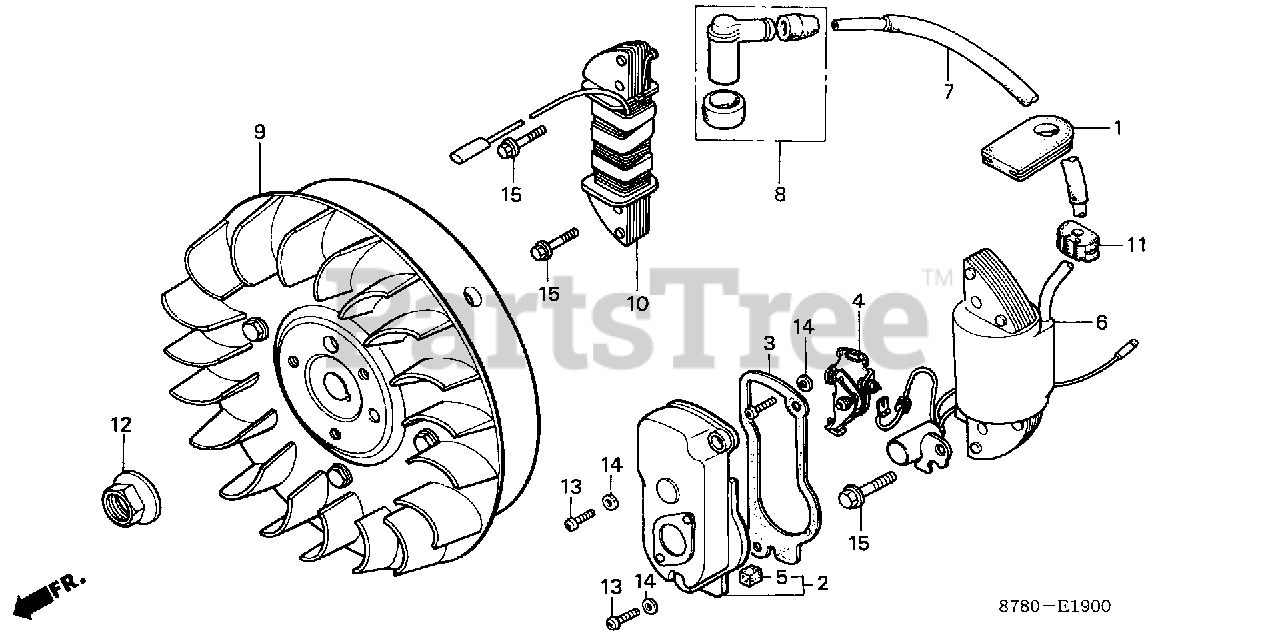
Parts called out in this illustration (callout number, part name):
1	GROMMET, CORD
2	COVER ASSY., BREAKER (NOT AVAILABLE)
2	COVER, BREAKER
3	GASKET, BREAKER COVER (NOT AVAILABLE)
4	POINTS ASSY.
6	COIL ASSY., IGNITION
6	COIL ASSY., IGNITION (DENSO) (NOT AVAILABLE)
7	TUBE, IGNITION RUBBER
8	TERMINAL ASSY., IGNITION (NOT AVAILABLE)
9	FLYWHEEL ASSY.
10	COIL ASSY., LAMP
11	GROMMET, WIRE
12	NUT, SPECIAL (14MM)
13	SCREW, PAN (4X8)
14	WASHER, PLAIN (4MM)
15	BOLT, FLANGE (6X25) (NOT AVAILABLE)
